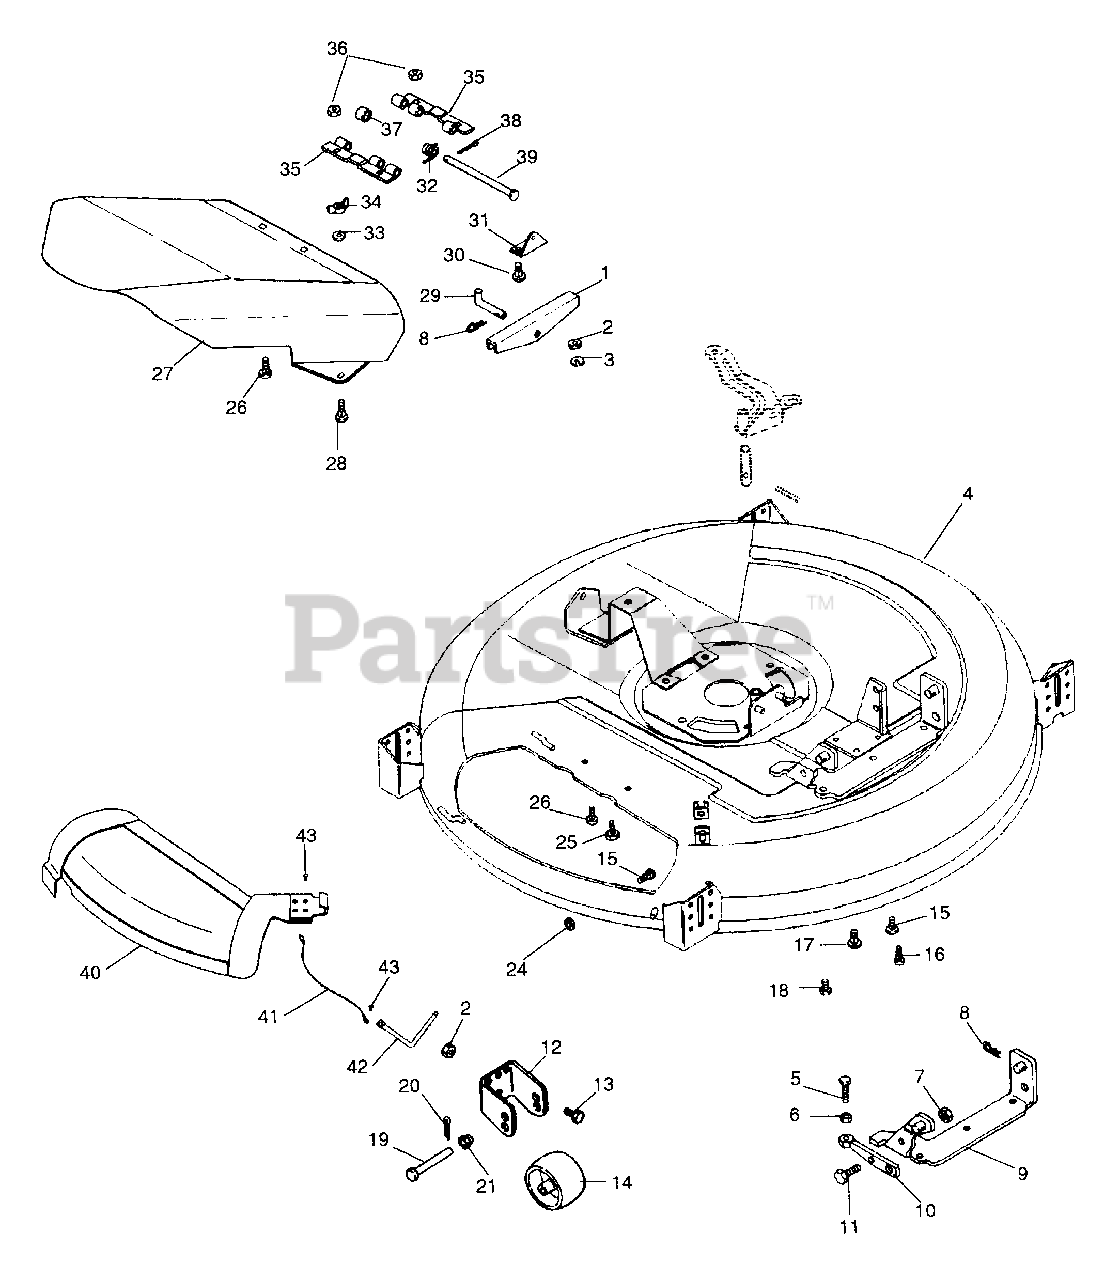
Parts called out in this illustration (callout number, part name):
1	SWIVEL BRACKET
2	NUT-FLG. .312-18 PL
3	WSHR-LK .312X.097 PL HVY
4	28"MOWER PAN W/DEFLECTOR&DECAL
4	28" MOWER PAN SERVICE ASSEMBLY
4	30"MOWER PAN W/DEFLECTOR&DECAL
4	30" MOWER PAN ASSEMBLY
4	32"MOWER PAN W/DEFLECTOR&DECAL
4	32" MOWER PAN SERVICE ASSEMBLY
5	BLT-HEX .38-16X1.25 PL GR5
6	NUT-JAM .375-16 PL
7	NUT-LK-CTR .375-16 GR A PL
8	PIN-HAIR INT .08X.38X1.42 YWZC
9	FRONT BRACKET 30"
10	ADJUSTING ARM
11	@BLT-HEX .38-16X.88 PL GR2
12	ROLLER CLEVIS
13	BLT-RDHDSQNK .312-18X.62SHTPL
14	ROLLER
15	BLT-RDHDSQNK .312-18X.62SHTPL
16	BLT-RDHDSQNK .25-20X.75
17	SCR-TAP .375-16X .50 HWH PL TR
18	BLT-RDHDSQNK .31-18X1.00 PL
19	PIN-CLEV .371X3.25 YWZC
20	PIN-COTR .15 X 1.0 PL
21	BSHG-FLG .372X.500X.312X.625NY
24	NUT-PUSH .312
25	BLT-RDHDSQNK .31-18X.75 GR5 PL
26	BLT-RDHDSQNK .25-20X.62 PL
27	PAN CHUTE EXTENSION
27	28" DEFLECTOR W/DECALS
27	32" DEFLECTOR W/DECAL
28	BLT-RDHDSQNK .25-20X1.00 GR5
29	CLEVIS PIN
30	SCR-TAP .312-18X.50 HWH PL TR
31	REAR MOUNTING BRACKET
32	SG-TORS .095X.50X 1.0
32	SG-TORS .090X.37X.63
33	WSHR-FL-STL .328X.875X.062 PL
34	NUT-WING W/INSERT .312 - 18
35	HINGE PLATE
36	NUT-LK-CTR .250-20 PL
37	BSHG-SLV .334 X .502 X 1.437
38	PIN-COTR .09X.75 PL
39	CLEVIS PIN
40	COVER WELDMENT 28"
41	LANYARD
42	PULL PIN
43	RVT-TBLR .187X.375 ST-AL PL
